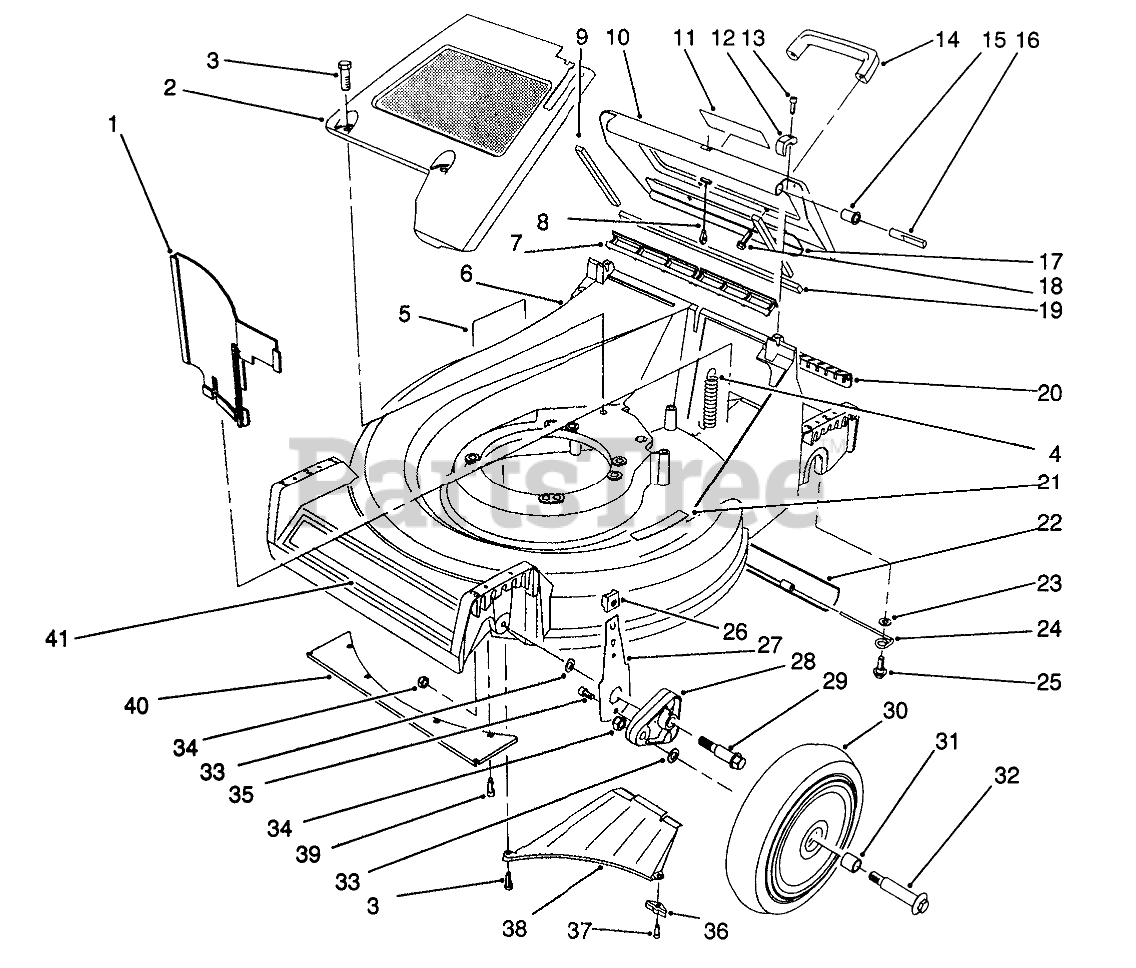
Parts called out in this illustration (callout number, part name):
1	PANEL-VERTICAL
2	PaneI-Screen
3	SCREW-HWHTF
4	EXTENSION-SPRING
5	Decal Danger
6	Housing-53cm (Incl. Ref. #5 & 21)
7	DOOR SEAL
8	DOOR CABLE
9	DOOR SIDE SEAL
10	Door-Discharge (Incl. Ref. #9, 11 & 19)
11	DECAL - DANGER
12	HINGE CLAMP
13	SCREW-HSH
14	HANDLE-DOOR
15	DOOR BUSHING
16	HINGE PIN
17	DOOR - BRACE
18	SCREW-HWH
19	DOOR END SEAL
20	ACCESS COVER
21	DECAL - STEP PAD INT'L
22	TRAILING SHIELD
23	WASHER-PLAIN
24	SHIELD HANGER
25	SCREW-SHOULDER
26	KNOB-ARM
27	FRONT SPRING ARM ASM
28	ARM-PIVOT, FRONT
29	Engine-OHV
30	Wheel & Tire Assembly (Incl. Ref. #31)
31	BUSHING
32	WHEEL BOLT
33	WASHER
34	NUT-LOCK
35	SCREW-HSH, THREAD FORMING
36	Bracket-Discharge
37	SCREW-HWHTF
38	Ramp Discharge
39	SCREW-HWH
40	FRONT GUARD
41	DECAL - 53 CM
